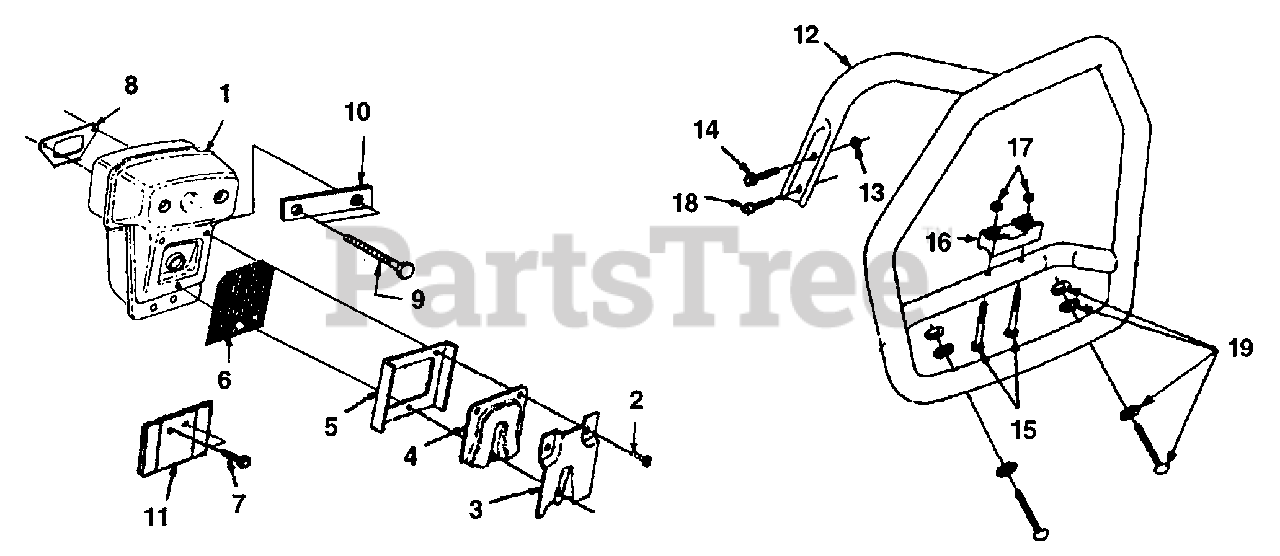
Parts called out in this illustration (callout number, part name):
1	MUFFLER ASSY.
2	SCREW-Mach. Hex (8-32 x 1/2")
3	SHIELD-Muffler
4	CAP-Muffler
5	SUPPORT-Spark Arrestor
6	SCREEN-Spark Arrestor
7	SCREW-Truss Hd. (10-24 X 3/4")
8	GASKET-Muffler
9	SCREW-Cap Hex Hd. (1/4-20 X 3 1/4")
10	SHIELD-Muffler Cover
11	PLATE-Retaining
12	HANDLE BAR
13	NUT-Hex Lock (10-24)
14	SCREW-Truss Hd. (10-24 X 3/4")
15	NUT-Locking (1/4-28")
16	BRACKET-Handle Bar
17	SCREW-Mach. Oval Hd. (1/4-20 X 1/2")
18	SCREW-Truss Torx (T25)
19	WEAR PAD KIT
